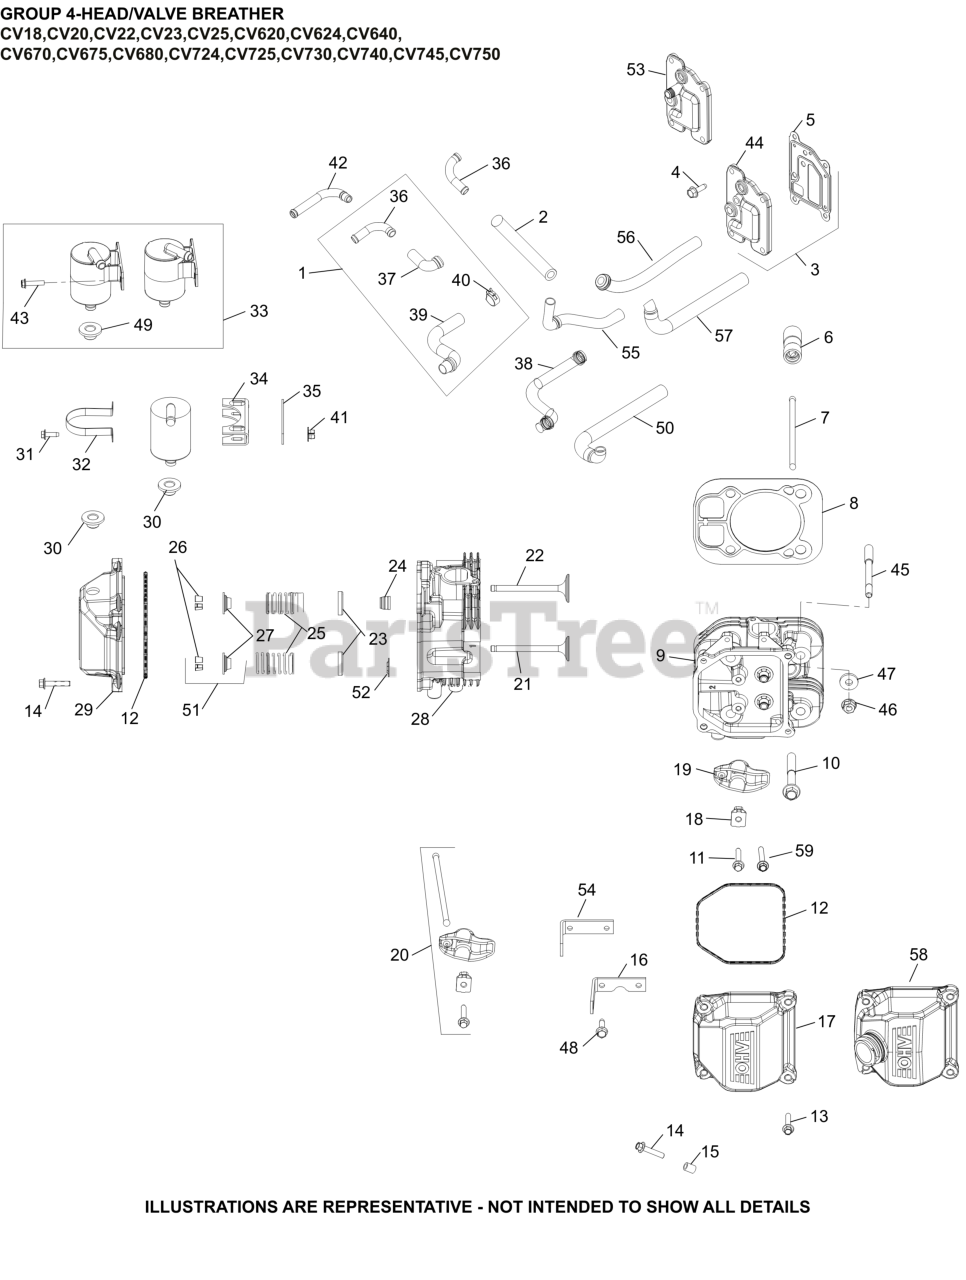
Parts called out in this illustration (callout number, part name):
2	HOSE, BREATHER -USE 24 326 63-S
3	KIT, BREATHER COVER W/GASKET
4	SCREW, THREAD FORMING
5	GASKET, BREATHER
6	LIFTER, VALVE HYDRAULIC-USE 25 351 11-S
7	ROD, PUSH
8	KIT, GASKET CYLINDER HEAD
9	KIT, CYLINDER HEAD (#2)
12	O-RING (YELLOW), VALVE CO
14	SCREW, FLG M6X1.0X30
16	STRAP, LIFT
17	KIT, VALVE COVER-PLAIN (PLASTIC)
18	PIVOT, ROCKER ARM
19	ARM, ROCKER
20	KIT, VALVE TRAIN
21	VALVE, EXHAUST
21	VALVE, EXHAUST (.25)
22	VALVE, INTAKE (STD)
22	VALVE, INTAKE (.25)
23	RETAINER, SPRING
24	SEAL, VALVE BAND
25	SPRING, VALVE
27	CAP, VALVE SPRING
29	KIT, VALVE COVER
33	KIT, BREATHER SEPARATOR
41	NUT, PLASTIC
45	STUD, M8X1.25
46	NUT, FLG M8X1.25
47	WASHER, FLAT 8.6 MM
48	SCREW, THREAD FORMING
49	GROMMET, RUBBER
51	KIT, RETAINER
52	RETAINER, VALVE GUIDE (KM)
59	SCREW,HEX FLANGE - USE 25 086 777-S
NI	KIT, CYLINDER HEAD (#1)
